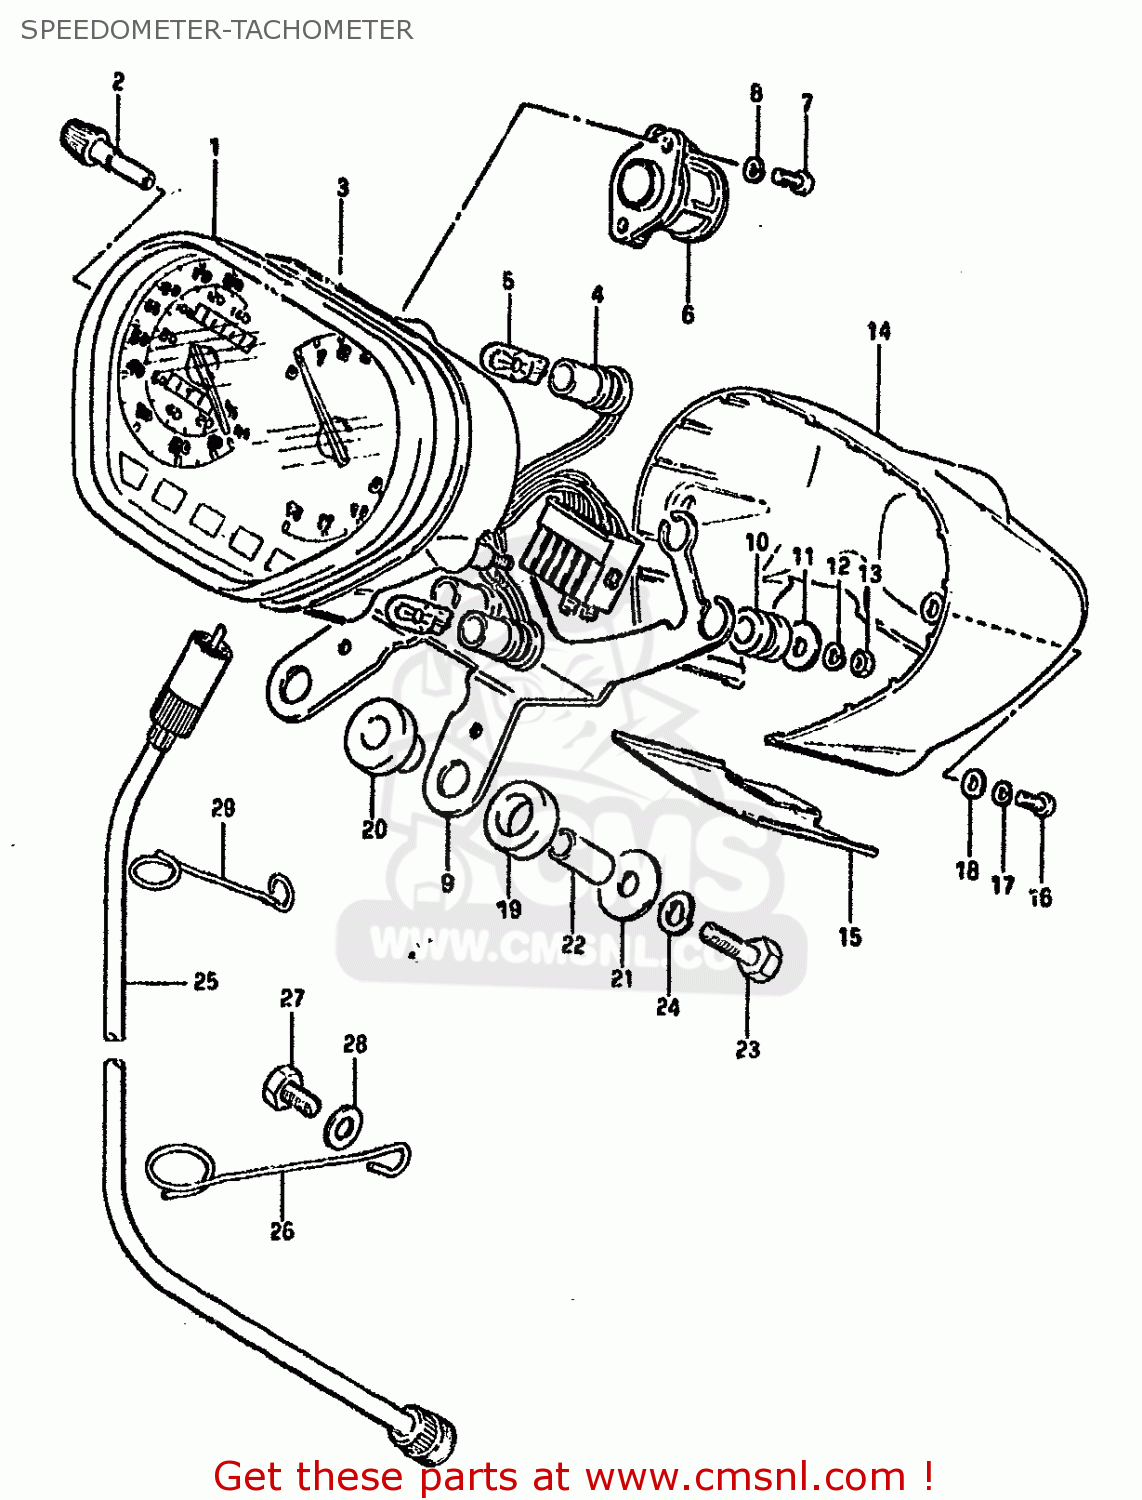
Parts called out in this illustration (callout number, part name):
1	SPEEDO & TACHOMETER
2	KNOB,TRIP METER
3	CUSHION
4	SOCKET
5	BULB(12V3.4W,T10)
6	GEAR BOX,SPEEDOMETER
7	SCREW 4X10
8	LOCK WASHER
9	BRACKET,METER
10	CUSHION
11	WASHER,COMBINATION METER
12	LOCK WASHER
13	NUT
14	COVER,LWR
15	PLATE,SPEEDOMETER
16	SCREW
17	LOCK WASHER
18	WASHER
19	CUSHION
20	CUSHION
21	WASHER (6.5X24X1.6)
22	SPACER (6.1X8X15.5)
23	BOLT
24	LOCK WASHER
25	CABLE ASSEMBLY,SPEEDOMETER
26	CLAMP,SPEEDOMETER CABLE
27	BOLT, UPPER
28	WASHER
29	GUIDE,SPEEDOMETER CABLE UPR
